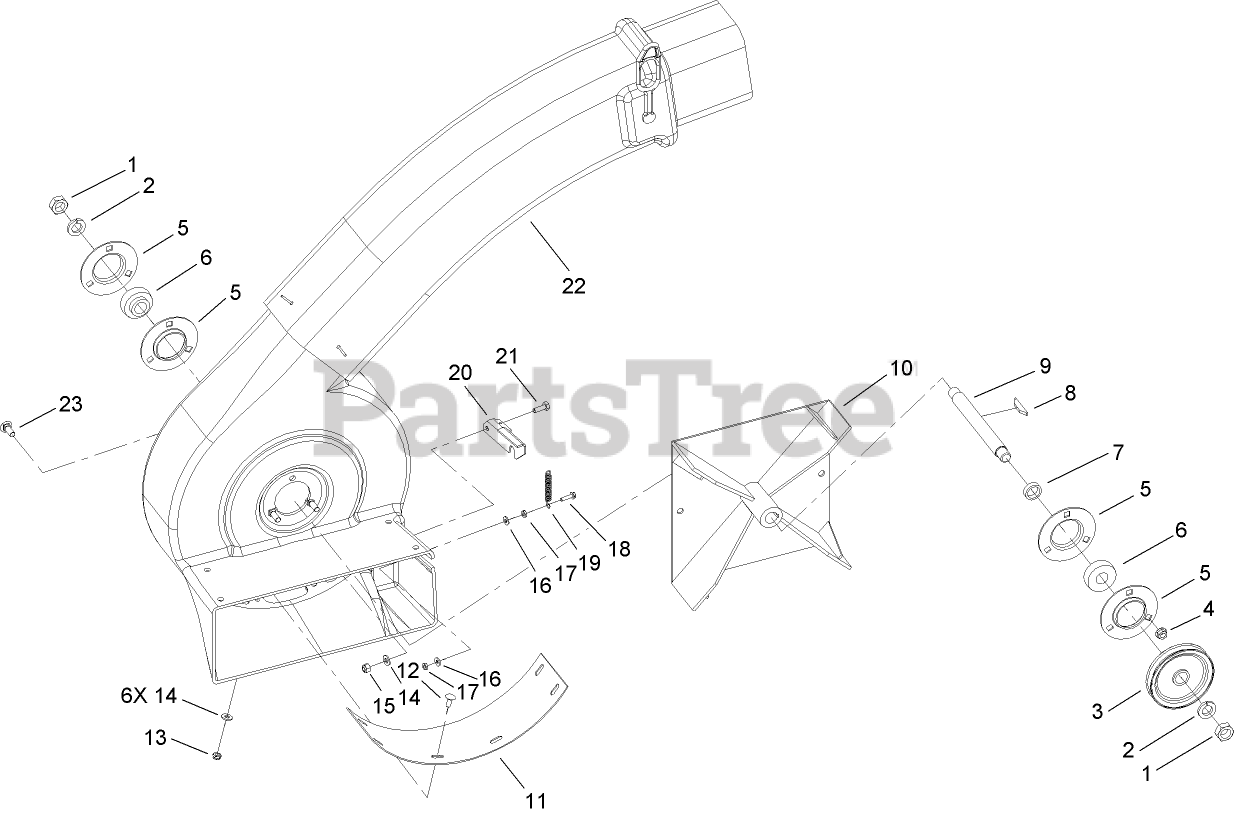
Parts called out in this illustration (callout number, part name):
1	NUT-JAM
2	WASHER-LOCK
3	PULLEY-BLOWER
4	NUT-HF
5	FLANGE
6	BEARING-BALL
7	SPACER
9	SHAFT-BLOWER
10	IMPELLER ASM
11	COVER-BLOWER, BOTTOM
12	SCREW-CARR
13	NUT-LOCK, NI
14	WASHER-FLAT
15	NUT-LOCK, NI
16	WASHER-FLAT
17	NUT-HEX
18	SCREW-HWH
19	SPRING-EXTENSION
20	LATCH-BLOWER
21	SCREW-HH
22	BLOWER HOUSING ASM
23	SCREW-CARR
